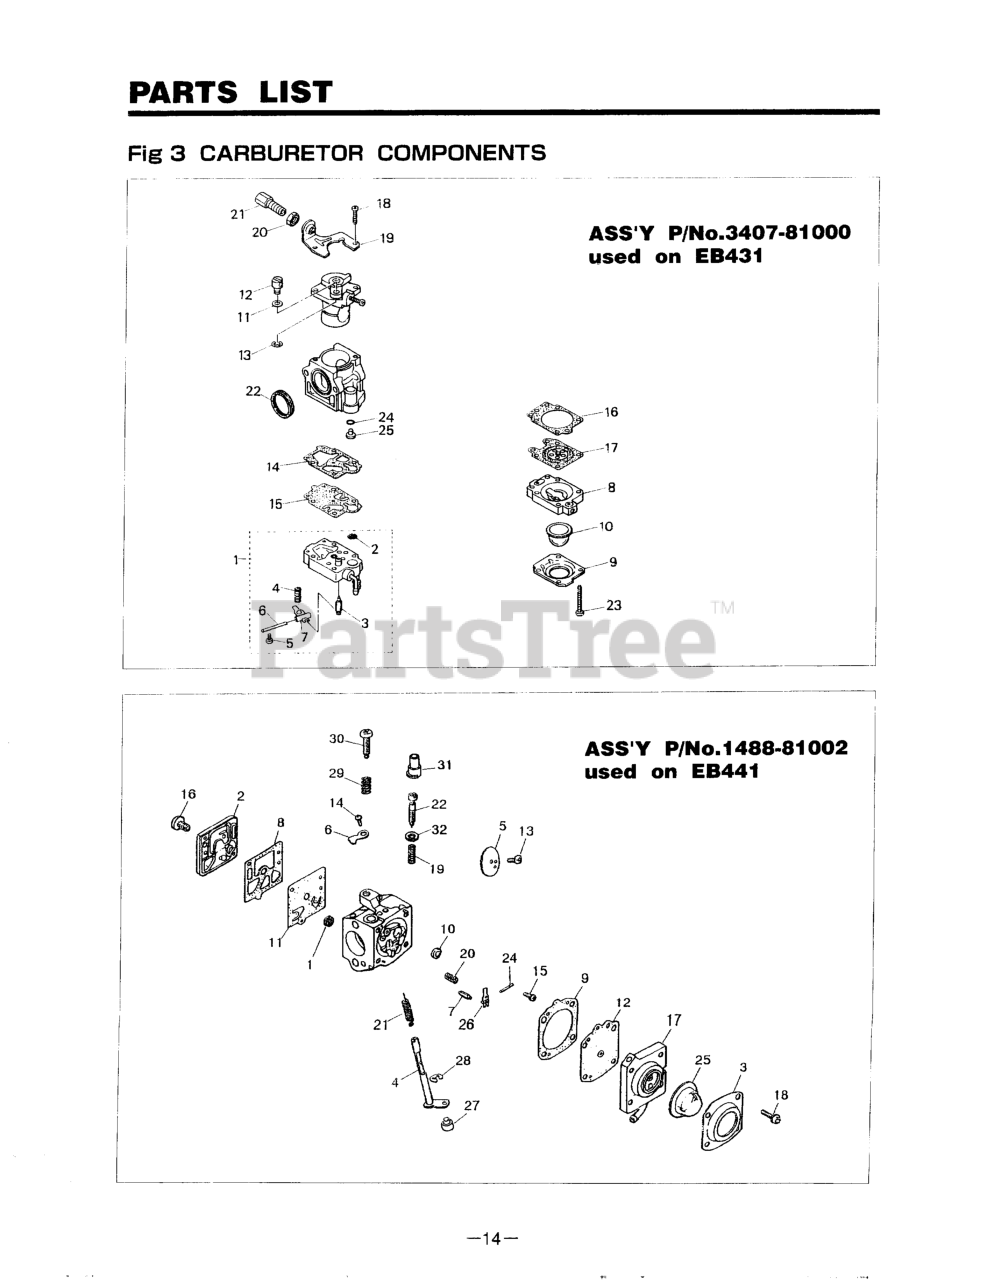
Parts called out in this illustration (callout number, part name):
1	BODY, PUMP
3	VALVE, INLET
4	SPRING, METERING LEVER
5	SCREW, METERING LEVER PIN
6	PIN, METERING LEVER
7	LEVER
8	BODY, PURGE
9	COVER, PUMP
10	PUMP, PRIMING
11	WASHER
12	SWIVEL
13	RING
14	GASKET, PUMP
15	DIAPHRAGM
16	GASKET, DIAPHRAGM
17	DIAPHRAGM (USE 4810-81260)
18	SCREW
20	NUT, CABLE ADJUSTER
21	SCREW, CABLE ADJUSTER
22	RING, PACKING
23	SCREW
25	RING, O
NI	CARBURETOR ASSEMBLY
